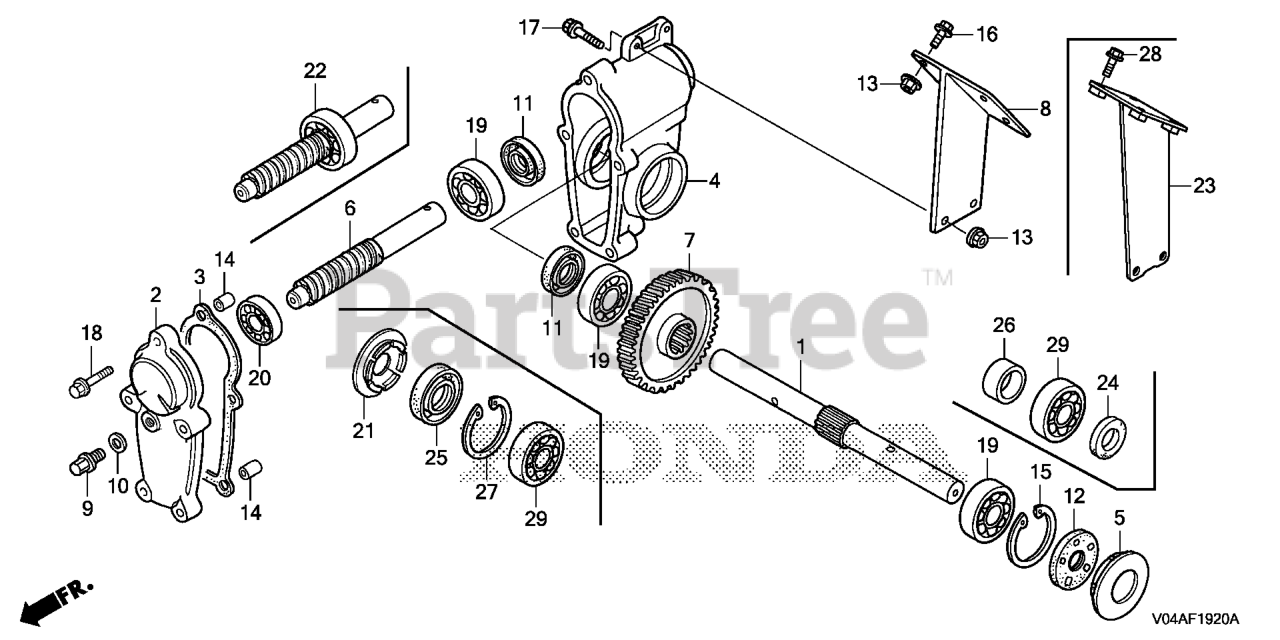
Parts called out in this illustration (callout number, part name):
1	SHAFT, AUGER
2	COVER, AUGER TRANSMISSION
3	GASKET, AUGER TRANSMISSION
4	CASE, AUGER TRANSMISSION
7	GEAR, DRIVEN (55T)
9	BOLT, DRAIN PLUG
10	WASHER, DRAIN PLUG (10.2MM)
11	OIL SEAL (20X32X7)
13	NUT, FLANGE (8MM)
14	PIN A, DOWEL (8X14)
17	BOLT, FLANGE (8X25)
18	BOLT, FLANGE (6X32)
20	BEARING, RADIAL BALL (6202)
21	CAP, AUGER CASE
22	GEAR, DRIVE (6T)
23	BRACKET, AUGER HOUSING
24	OIL SEAL (20X32X7)
25	OIL SEAL (20X42X8)
26	COLLAR, AUGER TRANSMISSION (A)
27	CIRCLIP (INNER) (42MM)
28	BOLT, FLANGE (8X18)
29	BEARING, RADIAL BALL (6004)
